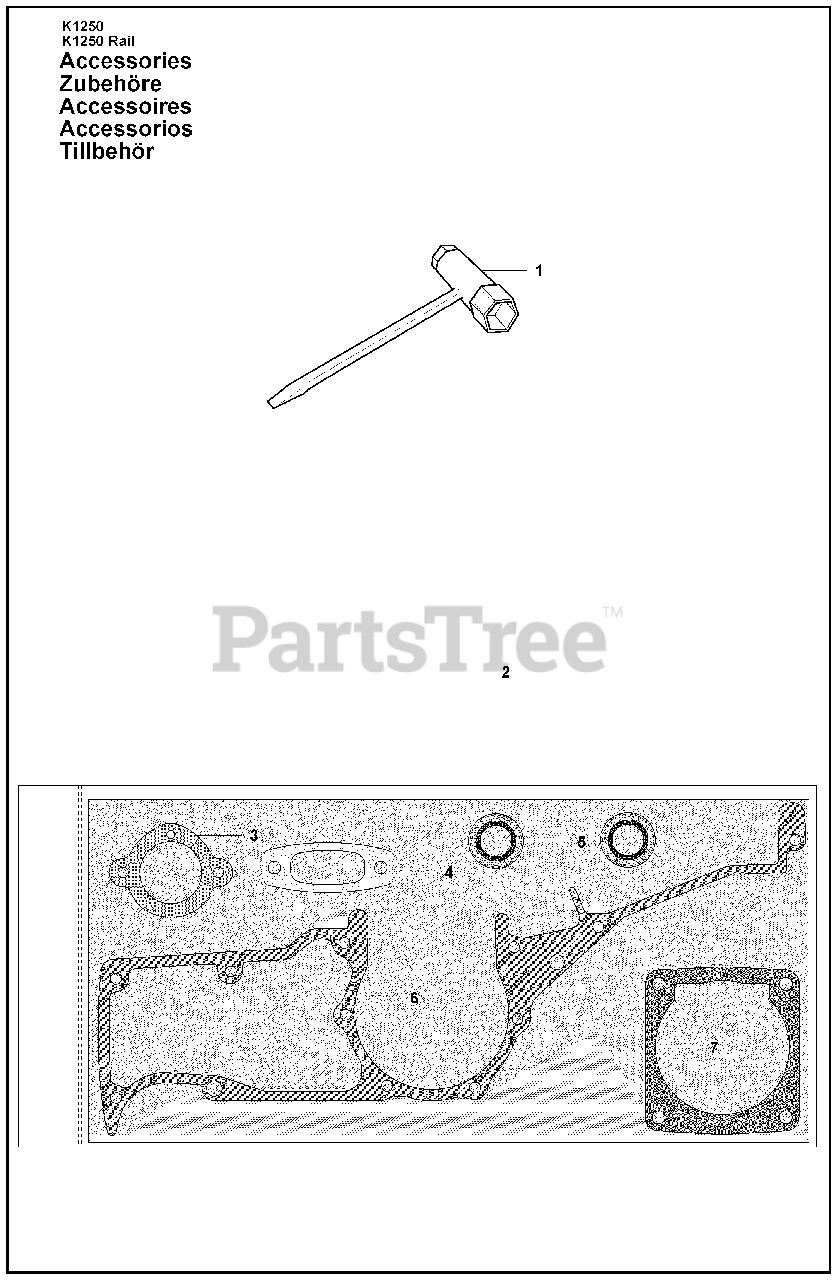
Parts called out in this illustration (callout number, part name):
1	COMBINATION TOOL
2	GASKET KIT
3	GASKET
4	GASKET MUFFLER
5	SEALING RING
6	CRANKCASE GASKET
